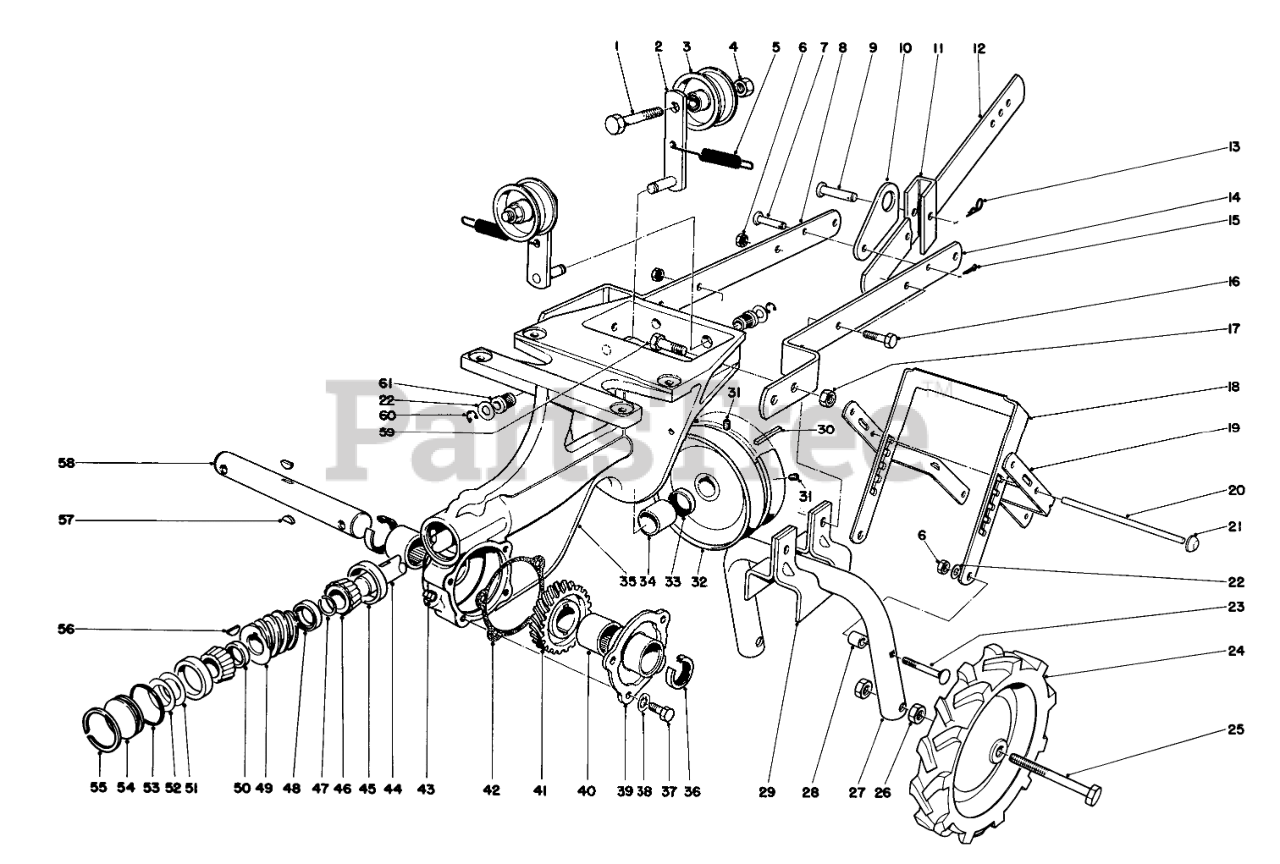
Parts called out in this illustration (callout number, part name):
1	Capscrew
2	00 Idler Arm
3	Pulley
4	NUT-LOCK, CONE
5	TENSION SPRING
6	NUT-LOCK, CONE
7	PIN-CLEVIS
8	Drawbar R.H.
9	CLEVIS
10	Latch-Depth Gauge
11	DEPTH GUAGE BRKT
12	Depth Gauge
13	PIN-COTTER, HAIR
14	Drawbar L.H.
15	PIN-COTTER
16	SCREW-HH
17	NUT-KEPS
18	Lever Wheel Adjustment
19	HANDLE SUPPORT
20	Shaft-Wheel Adjustment
21	PUSH ON
22	WASHER-PLAIN
23	BOLT-CARR
24	Wheel
25	Wheel Bolt
26	NUT-HEX
27	Axle Yoke
28	Spacer
29	Saddle Yoke
30	KEY-SQUARE
31	SCREW-SET
32	WORM SHAFT PULLEY
33	SEAL-OIL
34	BUSHING
35	Chassis
36	SEAL-OIL
37	1/4-20 X 5/8 CAPSCREW
38	WASHER-LOCK
39	Cover
40	Needle Bearing
41	WORM WHEEL
42	GASKET
43	PLUG-PIPE, SQH
44	WORM SHAFT
45	BEARING-ROLLER, CUP
46	BEARING-CONE
47	RETAINER RING
48	Spacer Rear
49	WORM GEAR
50	SPACER
53	O-RING
55	INTRNL RETAINING RING
56	KEY-WOODRUFF
57	KEY-WOODRUFF
58	WORM WHEEL SHAFT
59	SCREW-HH
60	RING-RETAINING, EXT
61	IDLER BRG
